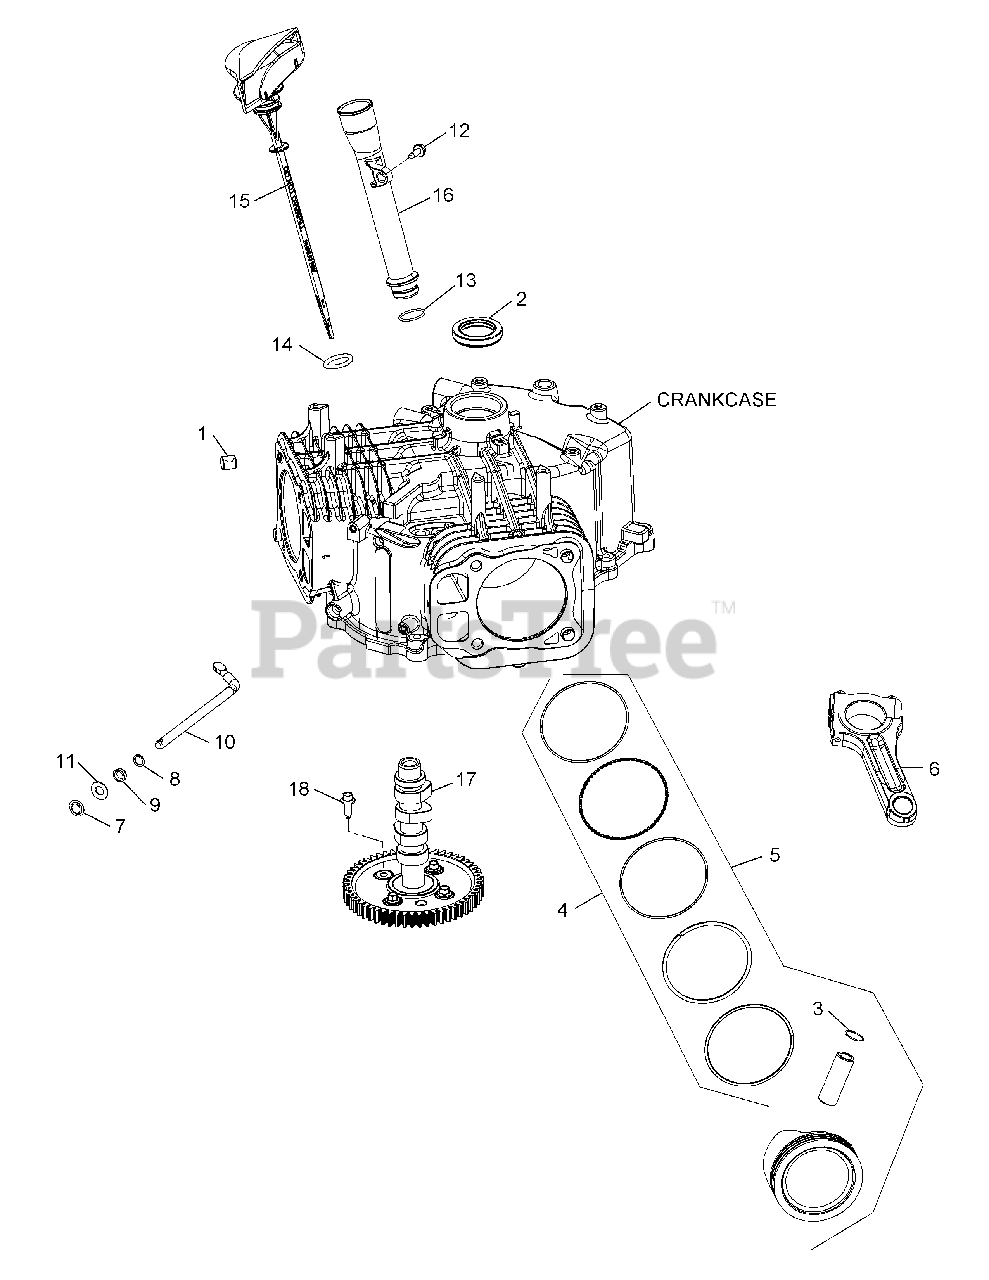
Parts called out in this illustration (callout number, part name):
3	Piston Pin Retainer
4	RING SET(STD)STYLE B-1.2mm Tp RING THICK
4	RING SET(.08)STYLE B-1.2mm Tp RING THICK
4	RING SET(.25)STYLE B-1.2mm Tp RING THICK
4	RING SET(.50)STYLE B-1.2mm Tp RING THICK
5	Piston Kit w/ Ring (STD) (Inc. 9 & 10)
5	Piston Kit w/ Ring (.08)
5	Piston Kit w/ Ring (.25)
5	Piston Kit w/ Ring (.50)
6	Connecting Rod Assembly (STD)
6	Connecting Rod Assembly (.010") (25mm)
7	Ring Retainer
8	Flat Washer, 11/32"
9	Governor Cross Shaft Seal
10	Governor Cross Shaft
11	Flat Washer, 9 mm
12	Thread Forming Screw
13	O-Ring
15	Dipstick Assembly
16	Oil Fill Assembly Tube
17	Camshaft Assembly
18	Hex Flange Screw
